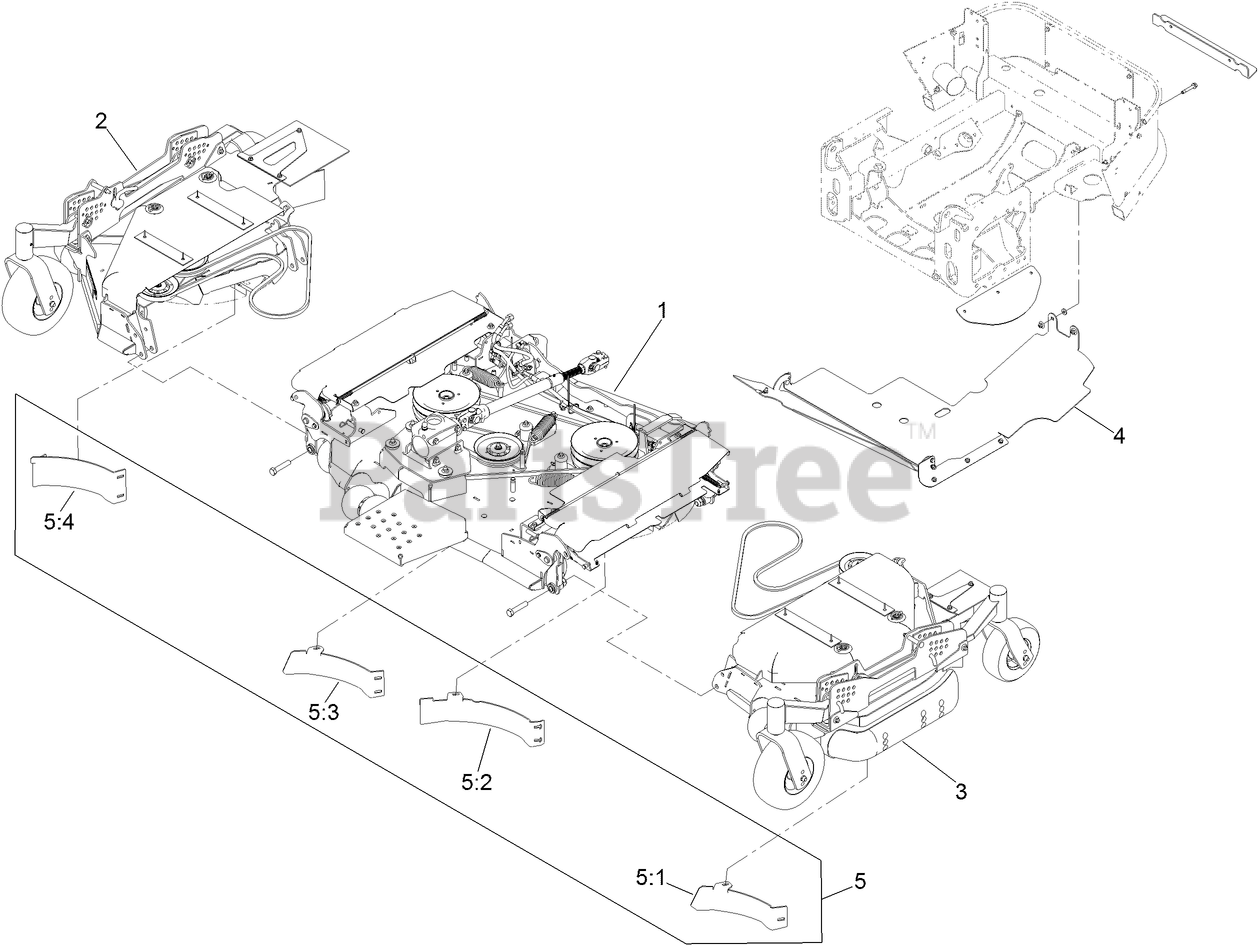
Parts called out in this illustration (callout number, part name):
1	CENTER DECK ASM
2	RH WING DECK ASM
3	LH WING DECK ASM
4	DISCHARGE TUNNEL ASM
5	KIT-96RD MULCH
5:1	BAFFLE-BLOCK
5:2	BAFFLE-BLOCK, LH CTR
5:3	BAFFLE-BLOCK, RH CTR
5:4	BAFFLE-BLOCK, RH WING
